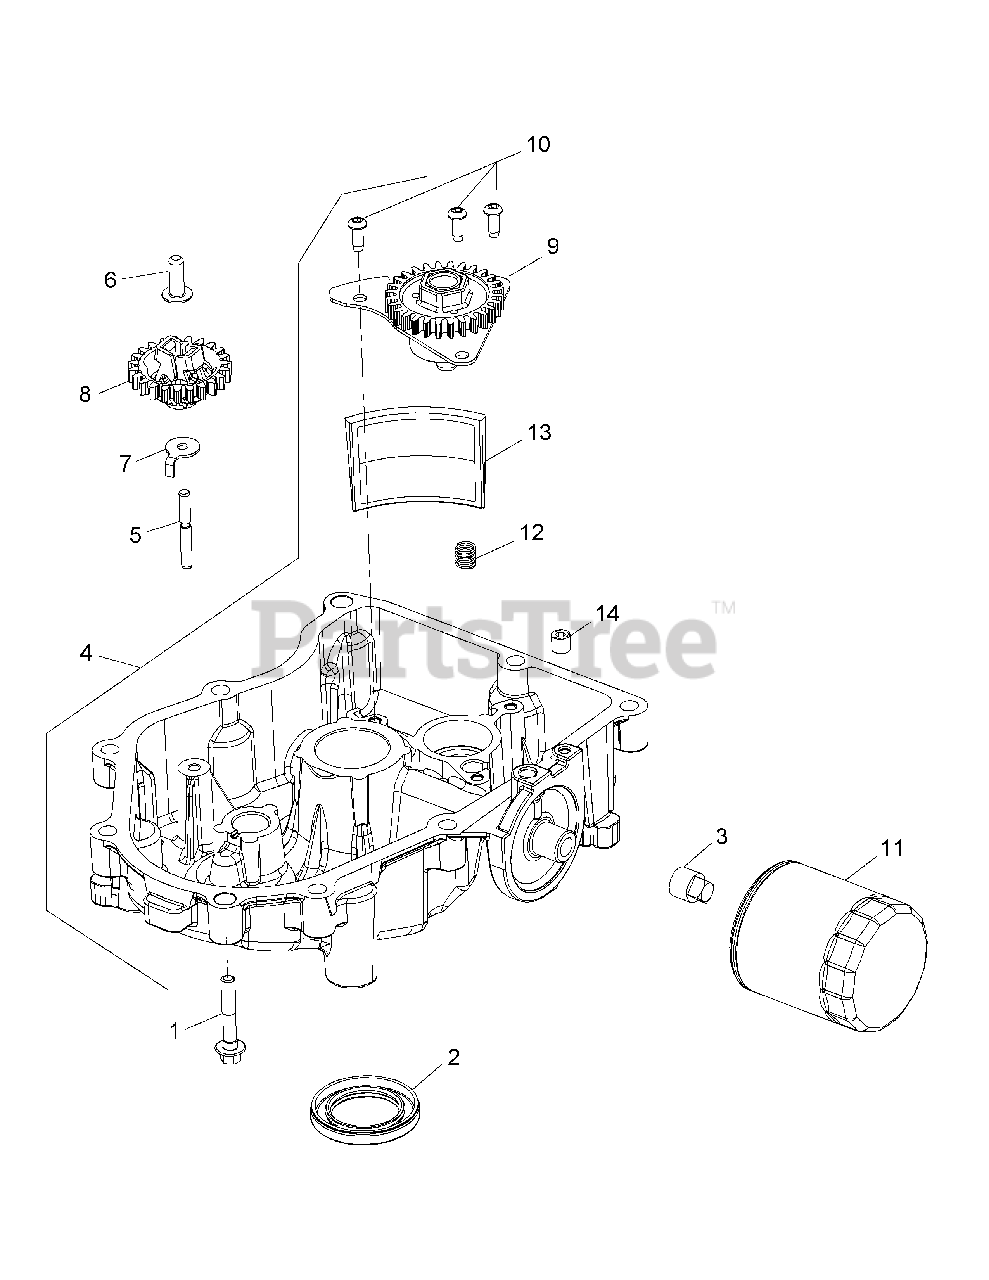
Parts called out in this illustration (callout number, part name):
1	Flange Screw, M8 x 1.25 x 45
2	Oil Seal, 2.38 x 1.45
3	Square Head Pipe Plug, 3/8
4	Oil Pan Assembly
5	Governor Gear Shaft
6	Governor Regulating Pin
8	Governor Gear Kit
9	Oil Pump Assembly
10	Button Head Screw
12	Compression Spring
14	Pipe Plug, 1/8
